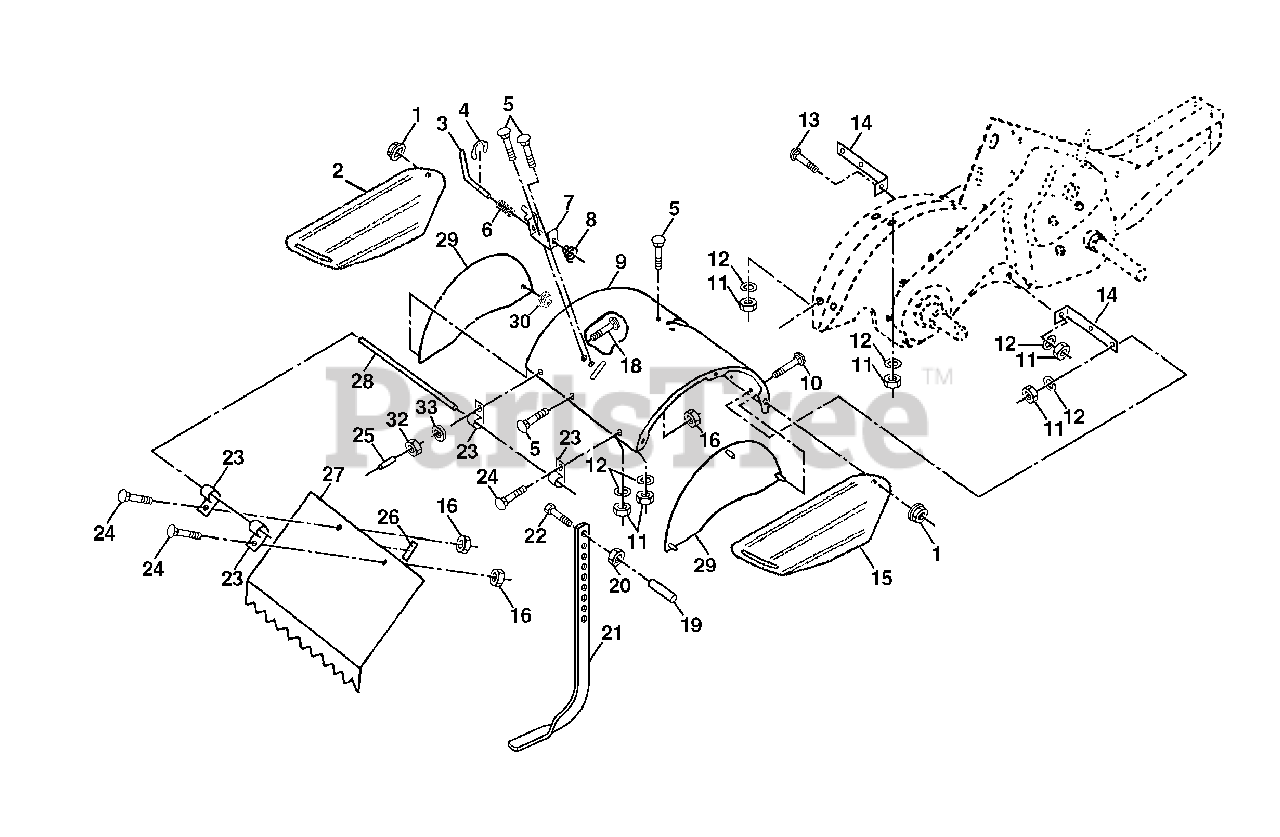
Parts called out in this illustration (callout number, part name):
1	Nut, Flange 5/16-18
2	Shield, Side, Outer L. H.
3	Pin, Stake, Depth
4	Ring, Klip
5	Bolt, Carriage 5/16-18 x 3/4 Gr. 5
6	Spring
7	Bracket, Latch
8	Spring, Depth Stake
9	Shield, Tine
10	Bolt, Carriage 5/16-18 UNC x 1
11	Nut, Hex 5/16-18
12	Washer, Lock 5/16
13	Bolt, Carriage 5/16-18 x 1-1/4
14	Bracket, Shield Tine
15	Shield, Side, Outer R.H.
16	Nut, Hex Flange 1/4-20 UNC
18	Bolt, Carriage 1/4-20 x 1-1/4 Gr. 5
19	Grip
20	Nut, Hex 3/8-16
21	Stake, Depth
22	Bolt, Hex 3/8-16 x 2
23	Hinge
24	Bolt, Carriage 1/4-20 x 1/2 Gr. 5
25	Cap, Vinyl
26	Pad, Idler
27	Shield, Leveling
28	Pin, Hinge
29	Shield, Side
30	Locknut, Flange 5/16-18
32	Nut Fin Hex 1/4-20 UNC
33	Washer Lock Hvy Helical 1/4
